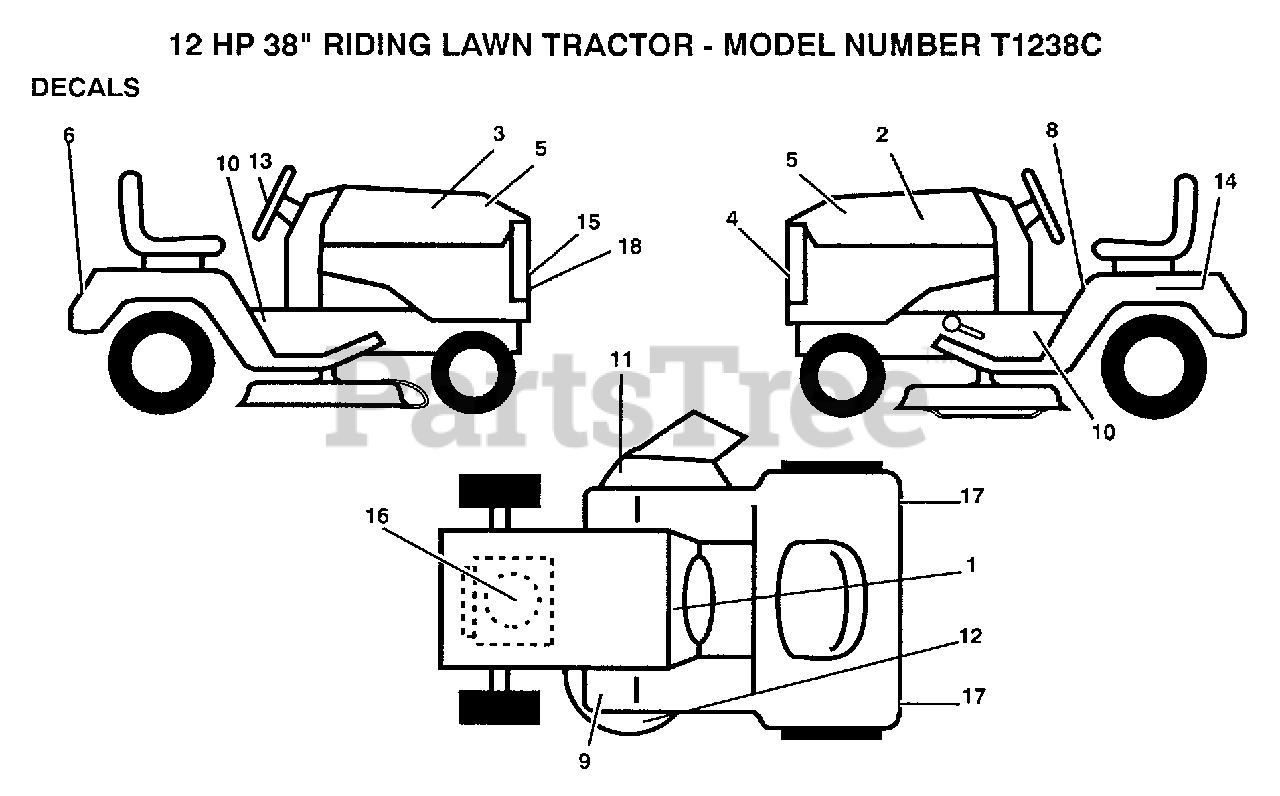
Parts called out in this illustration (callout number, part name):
2	DECAL, HOOD STRIPE LH
3	DECAL, HOOD STRIPR RH
4	"DECAL,GRILL"
5	DECAL HP HOOD
6	"DECAL,FENDER"
8	DECAL
9	DECAL T
11	DECAL WARNING
12	DECAL YT
13	"DECAL,STR WHL T"
14	DECAL
16	DECAL.ENG.271967
17	REFLECTOR-TAIL YT
18	DECAL.STRIPE.GR
